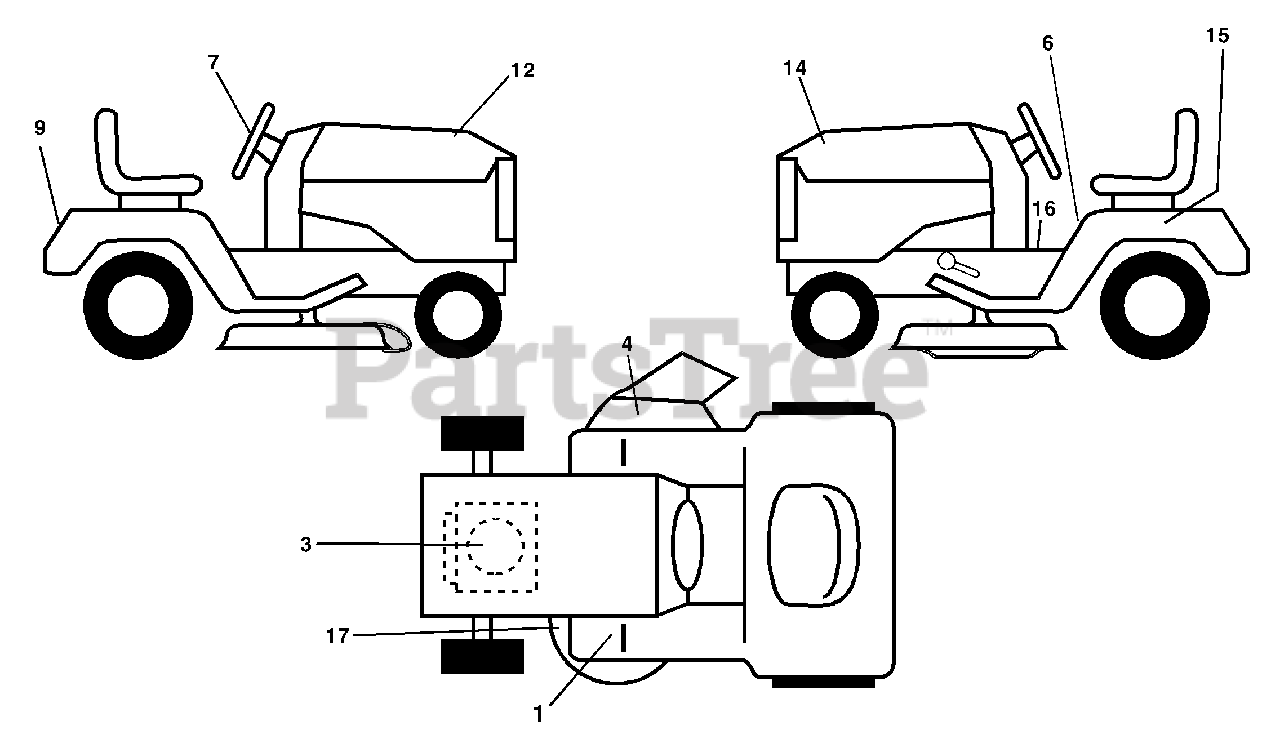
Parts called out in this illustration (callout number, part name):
1	Decal, Clutch/Brake Eng/Fr
3	Decal, Engine HP
4	Decal Warning
6	Decal, Fender Danger English
7	Decal Ins Str Wh
9	Decal Fender
12	Decal, Hood RH
14	Decal, Hood LH
15	Decal, Caution, Battery
16	Decal, Oper Sdl P/L Gear Dr Eng
17	Decal, V-Belt Sch.
